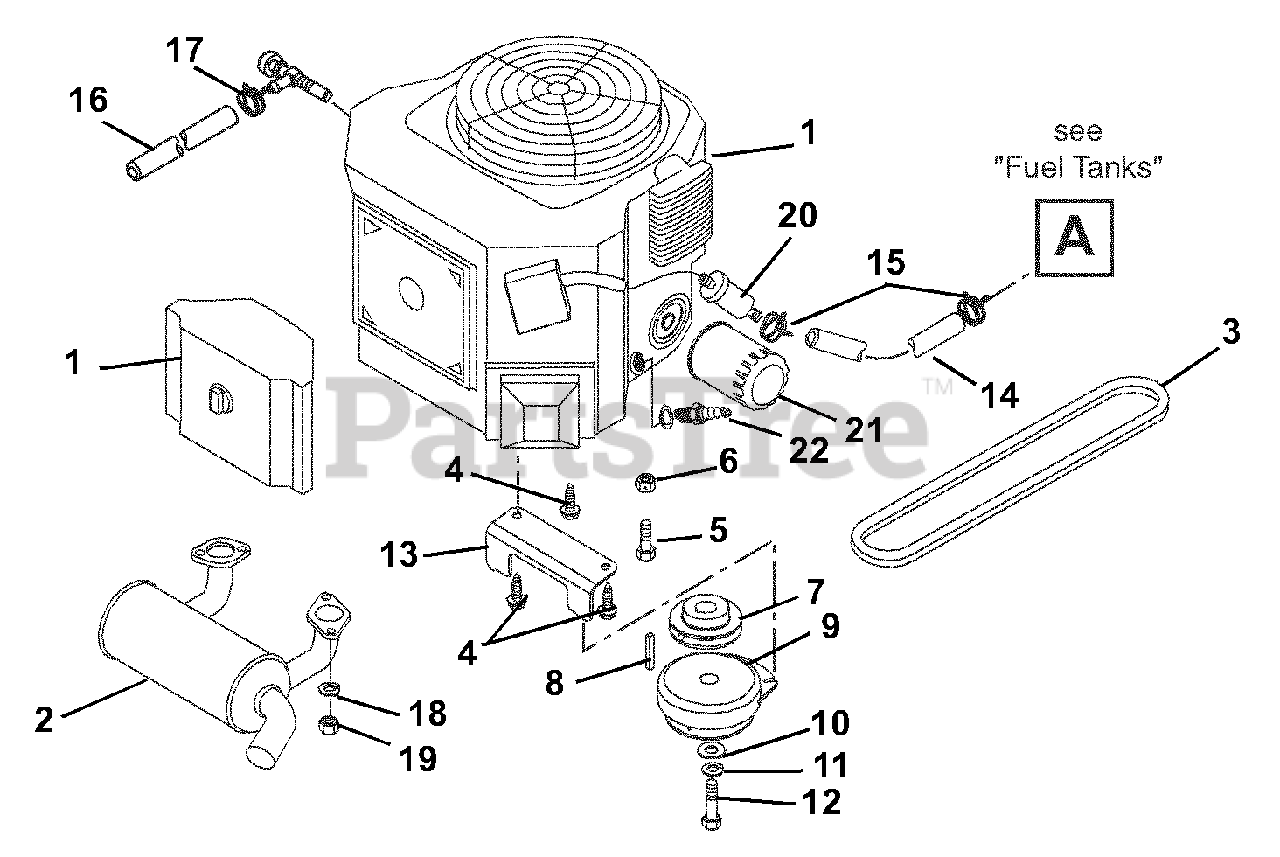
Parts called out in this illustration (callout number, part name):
1	Engine, 17HP FH500V Kawasaki
2	Muffler, Kawasaki
3	V-Belt HA 52 x .535 G48667
4	Screw, Tapping Hex Washer Head .38-16 x 1.00
5	Bolt, Hex .31-18 x 1.50 Grade 5
6	Nut, Locking Top Flange .31-18
7	Pulley, V 4.00 x 1.00
8	Key, Square .25 x .625 x .25 SAE 8630 OR SAE 1035
9	Clutch, Electric
10	Washer-Flat-Steel .469 x 2.00 x .25
11	Washer, Locking .44 x .109
12	Bolt, Hex .44-20 x 2.50 Grade 5
13	Bracket, Clutch
14	Hose, Gas Line 35"- .25" I.D.
15	Hose, Clamp
16	Hose, .50 x 6.00
17	Clamp, .88 Diameter Hose
18	Washer, Lock .31 x .078 Regular
19	Nut, Hex M8-1.25
20	Fuel Filter, Kawasaki
21	Oil Filter, Kawasaki
22	Spark Plug, Kawasaki
